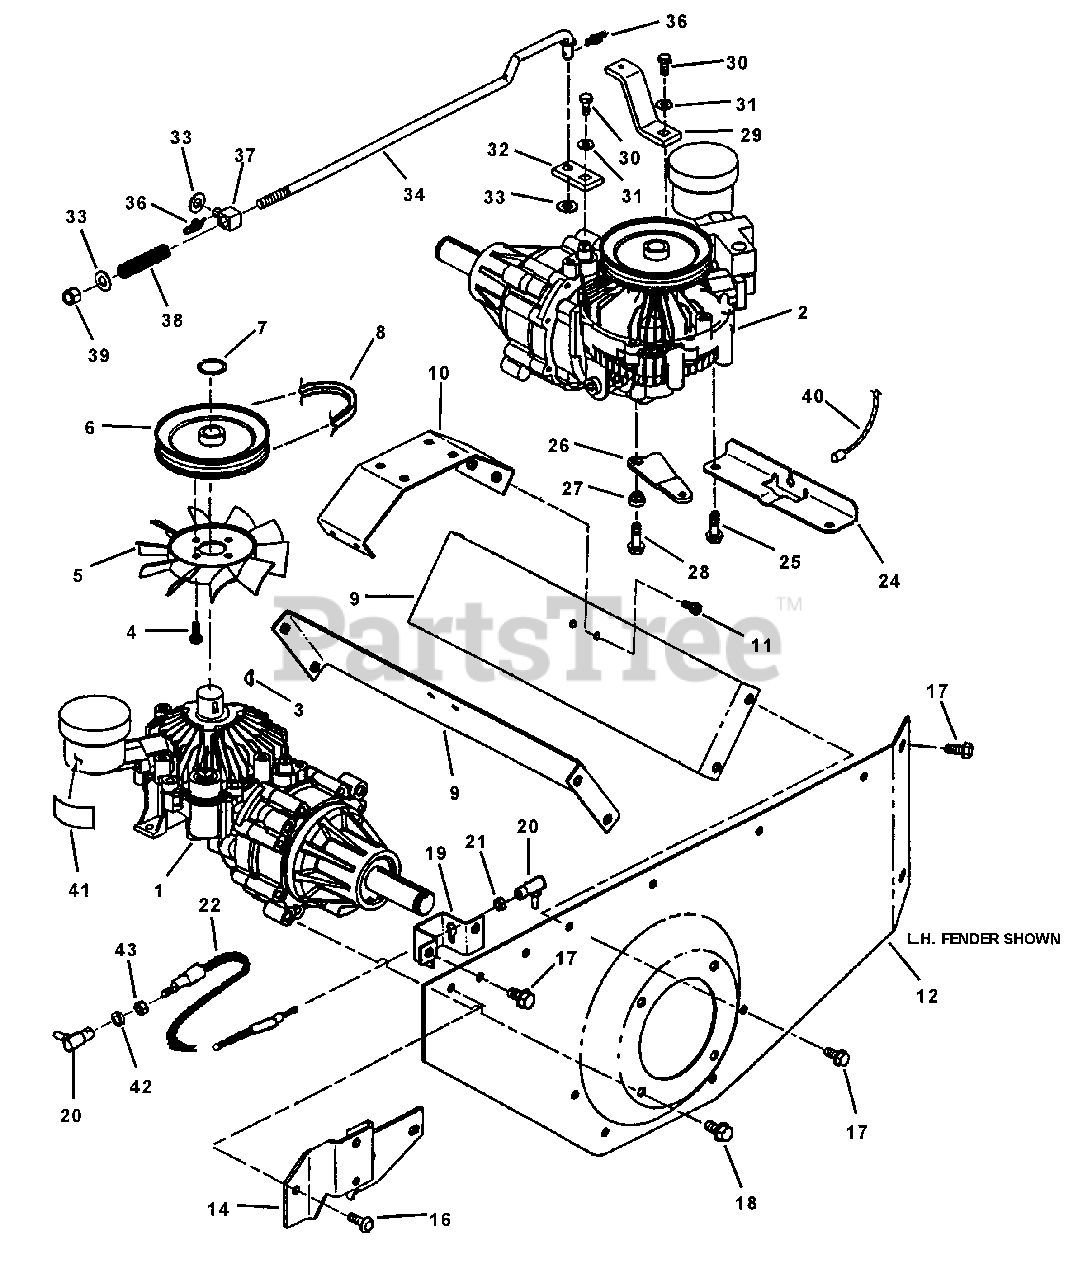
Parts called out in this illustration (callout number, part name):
1	TRANSAXLE, Hydro L.H.
2	TRANSAXLE, Hydro w/o Manifold R.H.
3	KEY, #605 Woodruff
4	SCREW, 1/4-20 x 1/2" Self-Tapping
5	FAN, 6" O.D., 10 Blade
6	PULLEY, Hydro Input
7	RING, Retaining
8	V-BELT, Hydro Drive
9	BRACKET, Fender Support
10	BRACKET, Hydro Support
11	SCREW, 1/4-20 Hex Washer Head, Self-Tapping
12	FENDER, L.H,
14	BRACKET, Deck Support L.H.
16	SCREW, 5/16-18 x 7/8" Pan Head, Self-Tapping
17	SCREW, 5/16-18 x 3/4" Hex Washer Head, Self-Tapping
18	SCREW, 3/8-16 x 1" Hex Washer Head, Self-Tapping
19	BRACKET, Hydro Control Cable
20	ROD END, #10-32 w/Stud
21	NUT, #10-32 Hex Center Lock
22	CABLE, L.H. Hydraulic Control
24	BRACKET, Hydro Release Cable
25	SCREW, 5/16-18 x 5/8" Hex Washer Head, Self-Tapping
26	BRACKET, Hydro Release Actuator
27	BUSHING,
28	SCREW, 5/16-18 x 1" Hex Washer Head, Self-Tapping
29	ARM, Brake
30	BOLT, 1/4-28 x 5/8" Hex Head, Grade 8
31	WASHER, 1/4 Belleville
32	ARM, Brake
33	WASHER, 3/8" Flat
34	ROD, R.H. Brake
36	COTTER-PIN, 3/8 Self-Locking
37	LINK, Swivel Brake
38	SPRING, Brake Compression
39	NUT, 3/8-16 Nyloc
40	CABLE, Hydro Release Valve
41	DECAL, Hydro Reservoir
42	WASHER, #10 Internal Tooth Lock
43	NUT, #10-32 Hex
